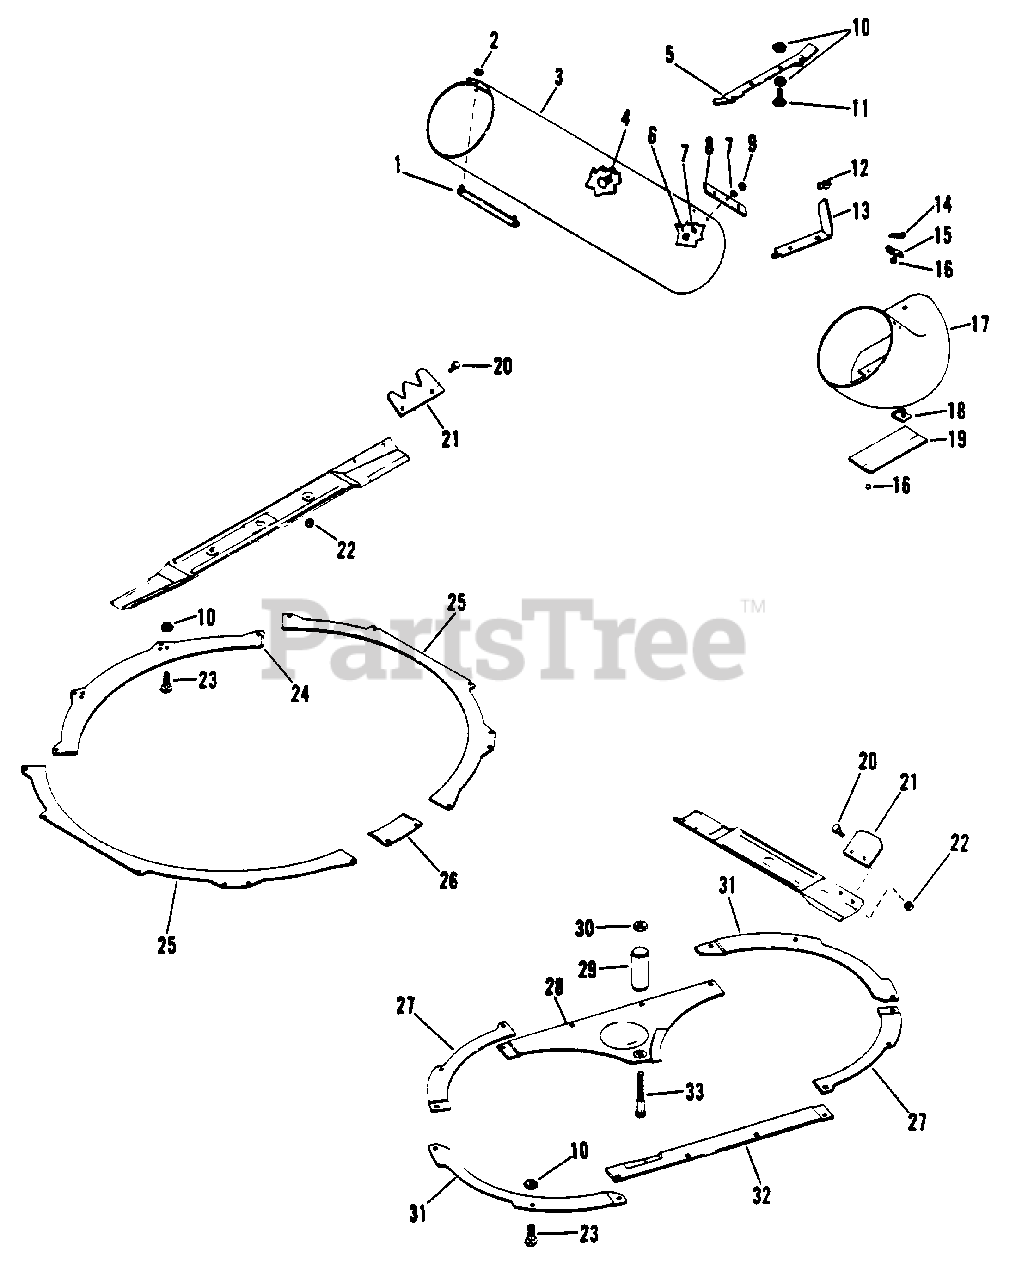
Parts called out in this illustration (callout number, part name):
1	Clip
2	Nut, Lock 1/4-20
3	Blank, Tube
4	Bolt, Carrige 1/4-20x.50
5	Spring, Latch
6	Screw, Machine 10-24x.50 PHD
7	Washer, Flat .219x.438x.049
8	Strap
9	Nut, Lock 10-24
10	Nut, Lock 1/4-20
11	Bolt, Carrige 1/4-20x1.25
12	Nut, Wing 5/16-18
13	Strap, Boot
14	Hairpin, Internal
15	Retainer
16	Rivet
17	Assembly, Boot w/Decal
18	Clip, Cone
19	Extension, Chute
20	Bolt, Hex 5/16-24x.75
21	Vane
22	Nut, Lock 5/16-24 Gr. C
23	Bolt, 1/4-20x.625 Rd Hd Sq Nk
24	Flange, Back
25	Flange, Side
26	Flange, Front
27	Flange, Short Curve
28	Flange, Rear
29	Spacer
30	Nut, Lock 1/2-13
31	Flange, Long Curve
32	Flange, Front
33	Bolt, 1/2-13x4.25 Rd Hd Sq Nk
